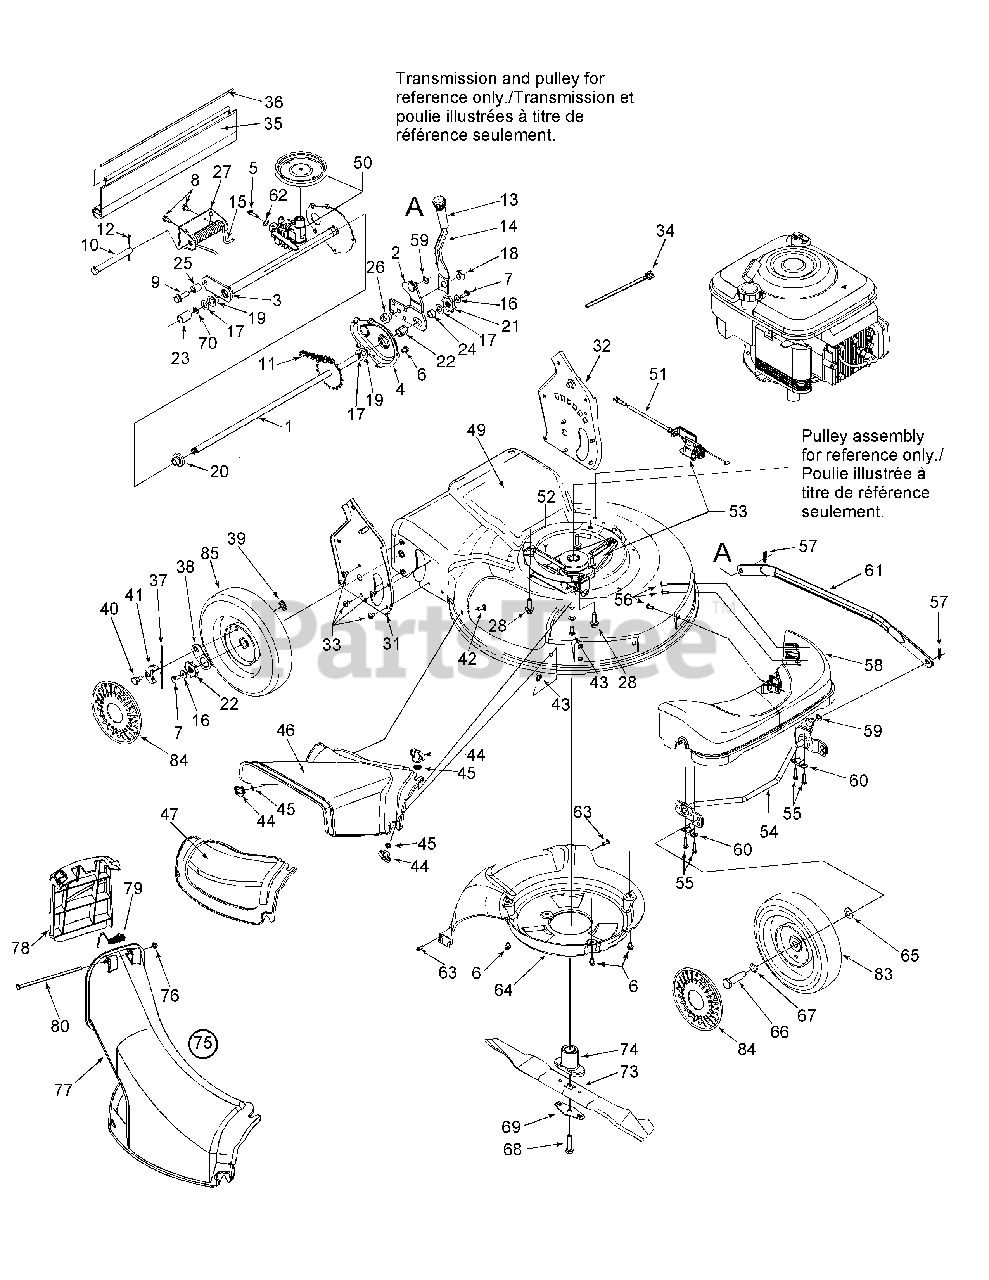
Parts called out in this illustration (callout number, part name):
1	Axle Ass’y 20T x 21.46" Lg.
2	Pivot Arm Ass’y
3	Trans Axle Ass’y
5	Hex Wash HD Screw 5/16-18 x .62
6	Hex Wash HD Tapp Screw 1/4-20 x .38
7	Hex Bolt 1/4-20 x .62
8	Hex Wash HD. TT Tap Screw 1/4-20 x .62
9	TT Screw 3/8-16 x 1.25
10	Clevis Pin .5" Dia. x 4.62" Lg.
11	Chain, No. 48 End less .50 x 24 links
12	Cotter Pin
15	RH Torsion Sprocket
16	Cupped Wash. .25 ID x .88 OD x .062
17	Washer, Flat .505 ID x 1.0
18	Shoulder Nut .625 DIA. x .165
19	Flange Bearing .506 ID
20	Hex Flange Bearing
21	Ratchet Wheel
22	Hex Sleeve Bearing .504 x .830 Lg.
23	Spacer .55 ID x .75
24	Sleeve .511 id x .70 od x .37" lg.
25	Spacer .38 x .625" Lg.
26	Shoulder Spacer .385 ID x .715" Lg.
29	Hex Wash Hd Screw 10-32 x 5/8
30	Clamp Casing - Throttle
33	Screw AB 1/4-20
35	Rear Flap 17.25" Lg.
37	Spring Nylon
38	Pawl Plate
39	Toplock Flat Weldnut 1/4-20
40	Shoulder Screw .340 x .285: 1/4-20
43	Carriage Bolt 1/4-10 x .75
44	Wing Nut
45	Flat Washer .260 x .720 x .060
47	Mulching Baffle
50	Transmission Ass’y
51	SP Cable 51.0" Lg.
52	V-Belt 3/8 x 39.24" Lg.
53	Pulley (6 speed Actuator)
55	Hex Wash. Hd. B-Tap Screw 1/4 x 1.0" lg
56	Torx Hd. Screw 5/16 x .75
57	Int. Cotter Pin 5/16 DIA
58	Front Cover- Black
59	Bowed Washer
60	Bushing Block .505 dia.
61	Single Lever Arm Control
62	Flat Washer
63	Screw 1/4-15 X .75
65	Cupped Wash .400 ID x .88 OD x .06
66	Axle Bolt
67	Wave Washer .51" ID
68	Hex Bolt 3/8-24 x 2.5" Lg.
69	Bell Blade Support
73	Blade 21" (Mulching)
74	Blade Adapter (w/star)
75	Chute Assembly
76	Push Cap .188 Rod
79	Torsion Spring
83	Front Wheel Ass'y 8 x 2.125 (Idle/ZagBall Brg)
84	Hub Cap -Grey
85	Rear Wheel Ass’y 9 x 2.125 (Drive/Zag/Blk)
